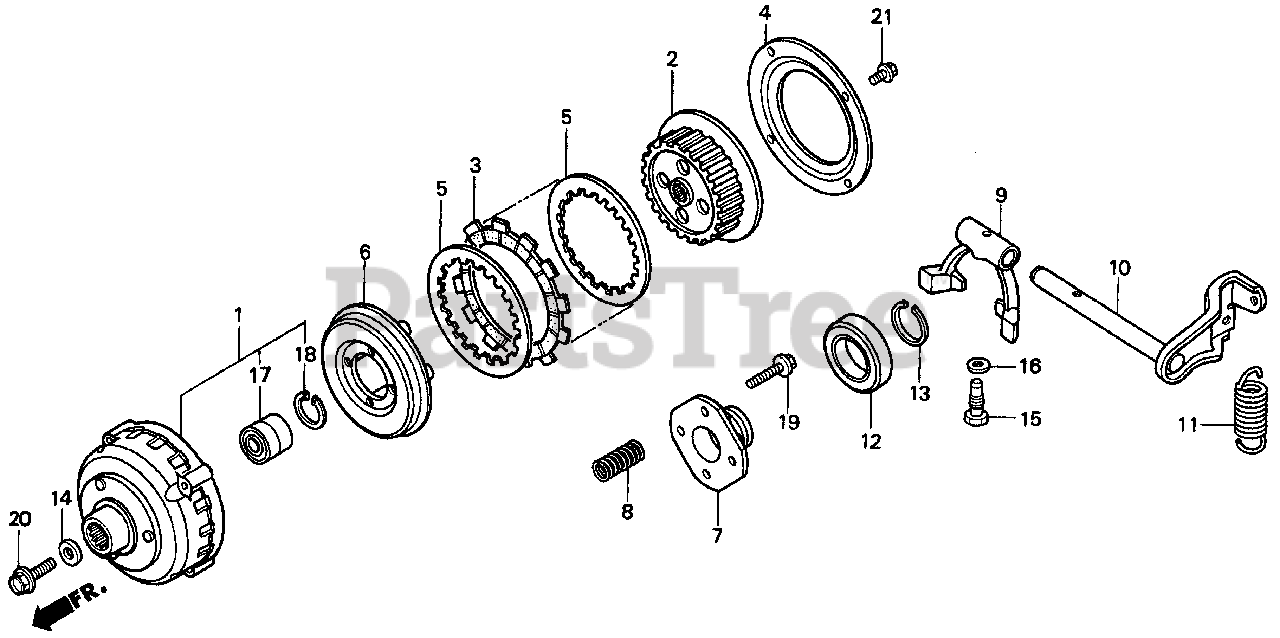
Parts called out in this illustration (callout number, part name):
1	CLUTCH (OUTER)
2	CENTER, CLUTCH
3	DISK, CLUTCH FRICTION
4	PLATE, BRAKE
5	PLATE, CLUTCH
6	PLATE, CLUTCH PRESSURE
7	PLATE, CLUTCH LIFTER
8	SPRING, CLUTCH
9	ARM, CLUTCH RELEASE
10	SHAFT, CLUTCH RELEASE
11	SPRING, RELEASE ARM
12	BEARING, CLUTCH RELEASE
13	RING, CLUTCH RELEASE BEARING SNAP
14	WASHER, PLAIN
15	BOLT, SPECIAL (8X24)
16	WASHER, CONICAL SPRING (8MM)
17	BEARING, SPECIAL BALL (6002)
18	CIRCLIP (INNER) (32MM)
19	BOLT, FLANGE (6X25)
20	BOLT, FLANGE (8X32)
21	BOLT, FLANGE (6X12)
